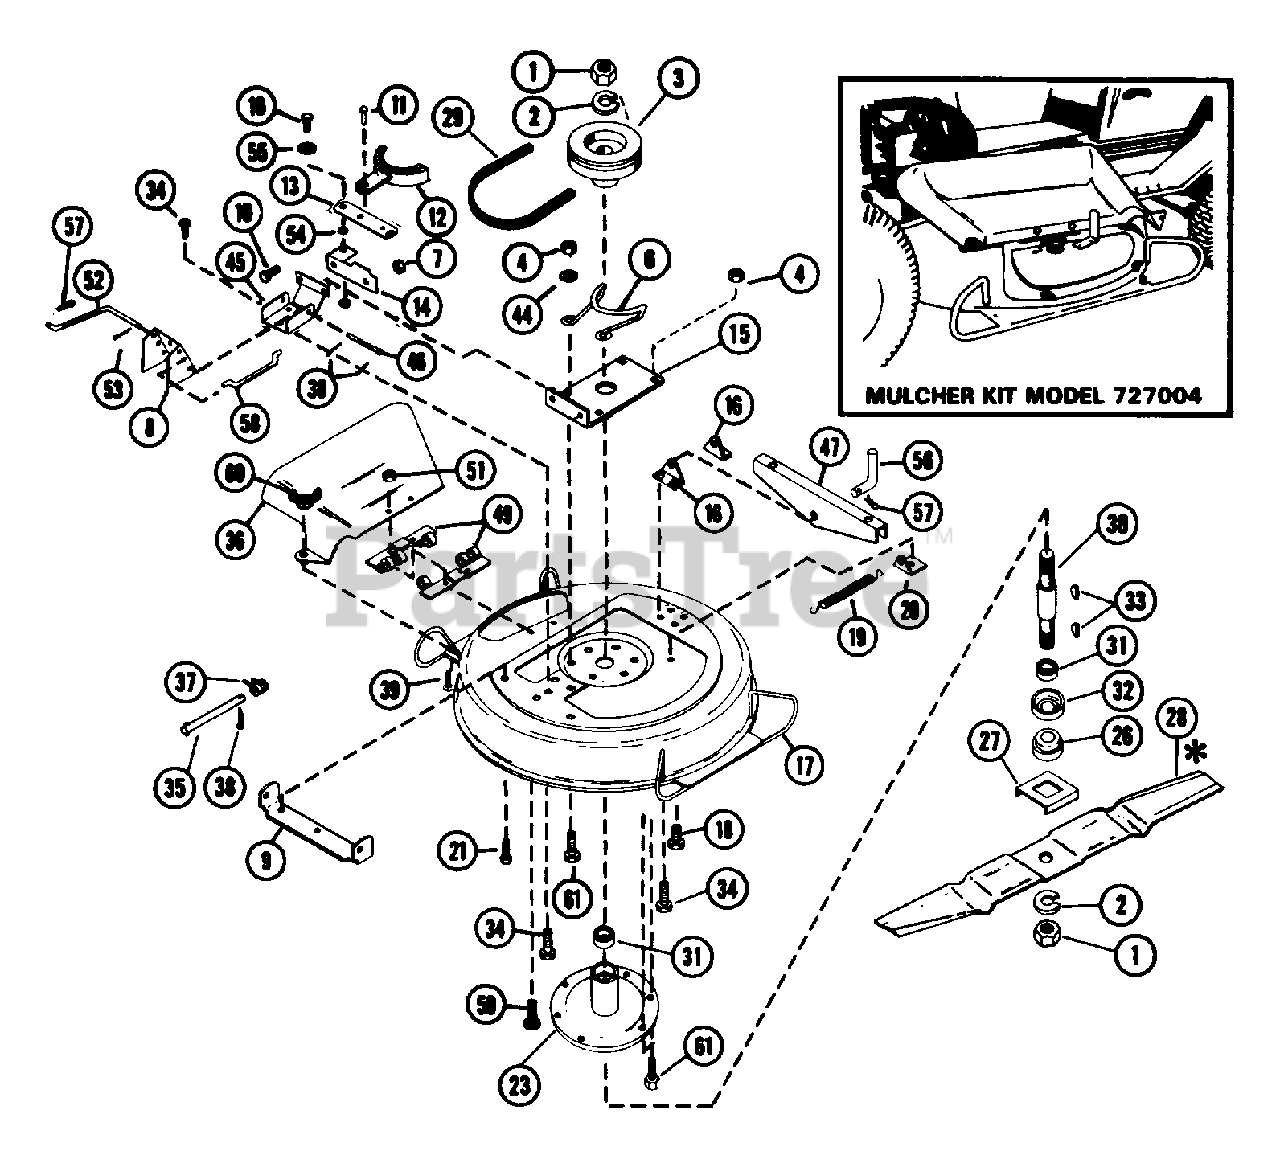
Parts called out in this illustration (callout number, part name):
1	NUT-JAM .75-10 PL
2	WSHR-LK .750X.188 MED PL
3	MOWER SHEAVE
4	NUT-LK-CTR .375-16 GR A PL
6	MOWER BELT FINGER
7	NUT-LK .312-18 GR A PL
8	MOWER ENGAGING ARM
9	FRONT MOUNTING BRACKET
10	BLT-HEX .31-18X.63 PL GR 2
11	RVT .25X.50 RH ST
12	BLADE BRAKE
13	MOWER BRAKE LEVER
14	BRAKE BRACKET
16	REAR MOUNTING BRACKET
17	28 MOWER PAN W/DECALS
18	BLT-SERHFWH .25-20X.50 PL
19	SG-TENS .072X.51X5.31 WLD 25
20	BRAKE CLIP
21	BLT-SCRHFWH .38-16X.50 PL
23	SPINDLE HOUSING
26	RETAINER HUB
27	BLADE TRAY
28	BLADE 28 IN
29	V-BELT
30	SPINDLE SHAFT
31	BRG-BALL .750X1.781X.61
32	BEARING SLINGER
33	KEY-WDRF .188X.75X.313 SAE 9
34	BLT-SERHFWH .31-18X.50 PL
35	CLEVIS PIN
36	DISCHARGE CHUTE
37	SG-TORS .090X.37X.63
38	PIN-COTR .09X.75 PL
39	BLT-RDHDSQNK .25-20X.75 GR5PL
44	WSHR-FL-STL .406X.865X.094 PL
45	PIVOT BRACKET
46	PIN-CLEV .309X3.50 SP
47	SWIVEL BRACKET
48	HINGE PLATE
51	NUT-LK-CTR .250-20 PL
52	MOWER ENGAGEMENT LINK
53	PIN-COTR .12X.75 PL
54	SPACER
55	WSHR-FL-STL .328X1.0X.094
56	CLEVIS PIN
57	PIN-HAIR INT .08X.38X1.42 YWZC
58	MOWER BRAKE LINK
59	BLT-RDHDSQNK .25-20X.62 PL
60	NUT-WING .250-20
61	BLT-HEX .38-16X1.00 PL
